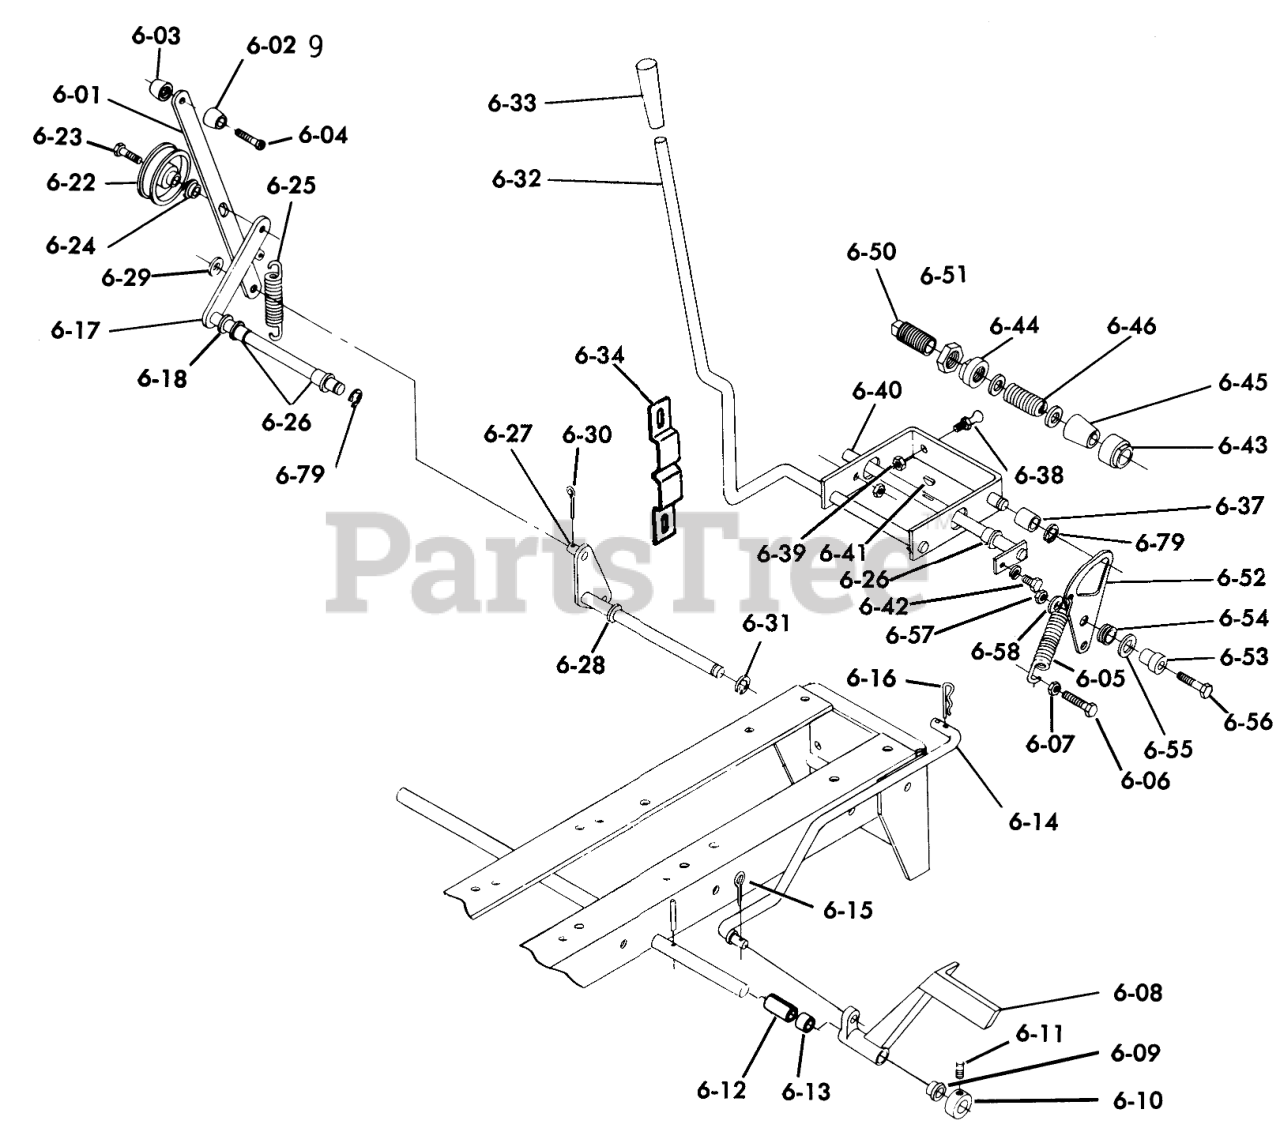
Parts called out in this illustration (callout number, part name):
6-01	HANDLE R (NS)
6-02	KNOB
6-03	KNOB
6-04	Machine Screw
6-05	Spring
6-06	Bolt
6-07	Nut
6-08	PEDAL R
6-09	BUSHING
6-10	Collar
6-11	SCREW-SET
6-12	SPACER
6-13	Spacer
6-14	Gasket
6-17	Idler Arm
6-18	Washer
6-18	Bolt
6-18	Nut
6-22	Idler Pulley
6-23	HEX HD CAP SCREW
6-24	SPACER-BRAKE LINK
6-25	SPRING-EXTENSION
6-26	BUSHING-FLANGED
6-27	ever Brake
6-28	Washer
6-29	Washer
6-30	Cotter Pin
6-31	E Ring
6-32	Cam Control
6-33	KNOB
6-34	SPRING-DETENT
6-34	WASHER 5/16 SAE
6-34	SCREW
6-37	BEARING-CAM RETURN
6-38	PIN
6-39	Nut
6-40	Cam Pivot Rod
6-41	WOODRUFF KEY
6-42	SCREW
6-43	FRICTION COLLAR
6-44	COLLAR BRKT PIVOT
6-45	FRICTION CONE
6-46	SPRING FRICTION
6-47	BUSHING-FLANGED
6-47	Washer
6-50	Collar Friction
6-52	Cam Plate
6-53	Spacer
6-54	NYLINER BUSHING
6-55	SHIM-WASHER
6-56	Bolt
6-57	Nut
6-58	Washer
